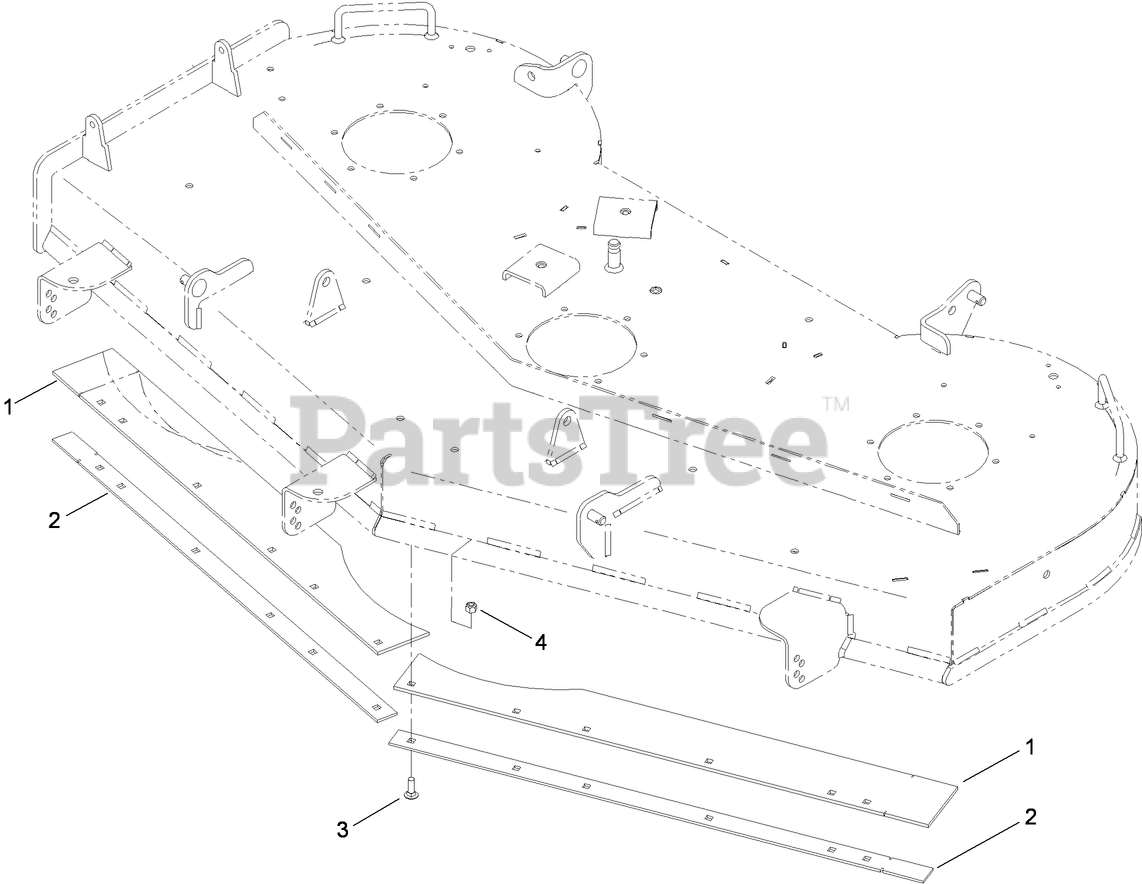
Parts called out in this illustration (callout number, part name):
1	SKIRT-RUBBER, FRONT
2	SKID-SKIRT
3	BOLT-CARR
4	NUT-LOCK, NI
